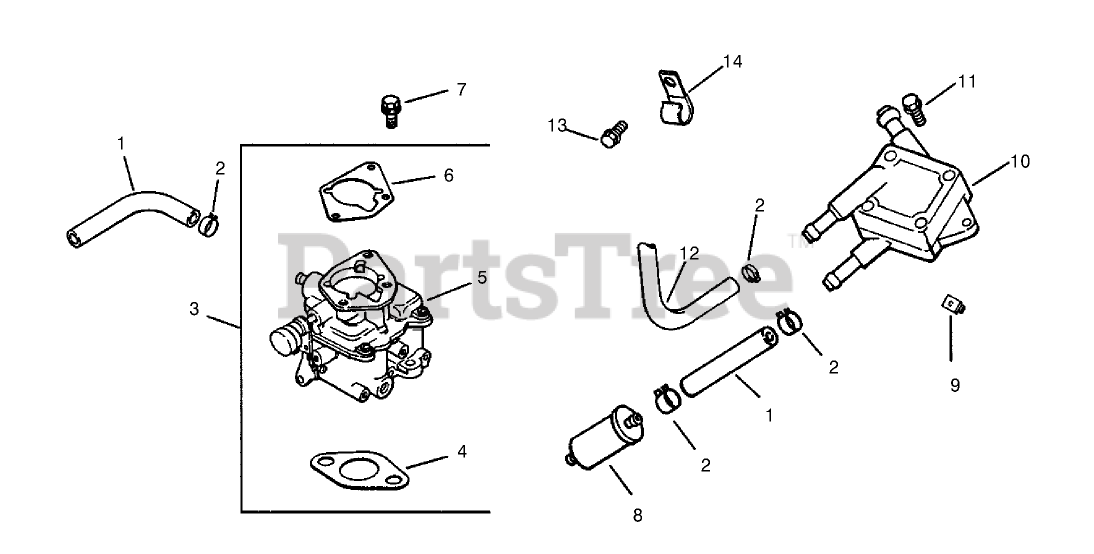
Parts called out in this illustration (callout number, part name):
1	Line-Fuel 9"
2	Clamp
3	Kit, carburetor w/gasket (Includes 4-6)
4	GASKET-BASE, AIR CLEANER
6	Gasket-Carburetor
7	SCREW-FLANGE (M6X1.0X30)
8	Filter-Fuel
9	Nut-Plastic
10	PUMP-FUEL
11	SCREW-TAP (M6X1.7X18)
12	Line-Fuel, Flexible (15.5)
13	Screw-HF (M6x1.0x12)
14	Clip, cable
15	Kit, solenoid (Includes 16-23)
18	O-Ring
19	O-Ring
21	Solenoid ASM
22	FLOAT REPAIR KIT
24	Clip-Valve, Needle Inlet
25	Valve-Needle, Inlet
26	Screw
27	Gasket-Body, Carburetor
29	O-Ring
31	O-Ring
33	Spring-Needle, Idle
